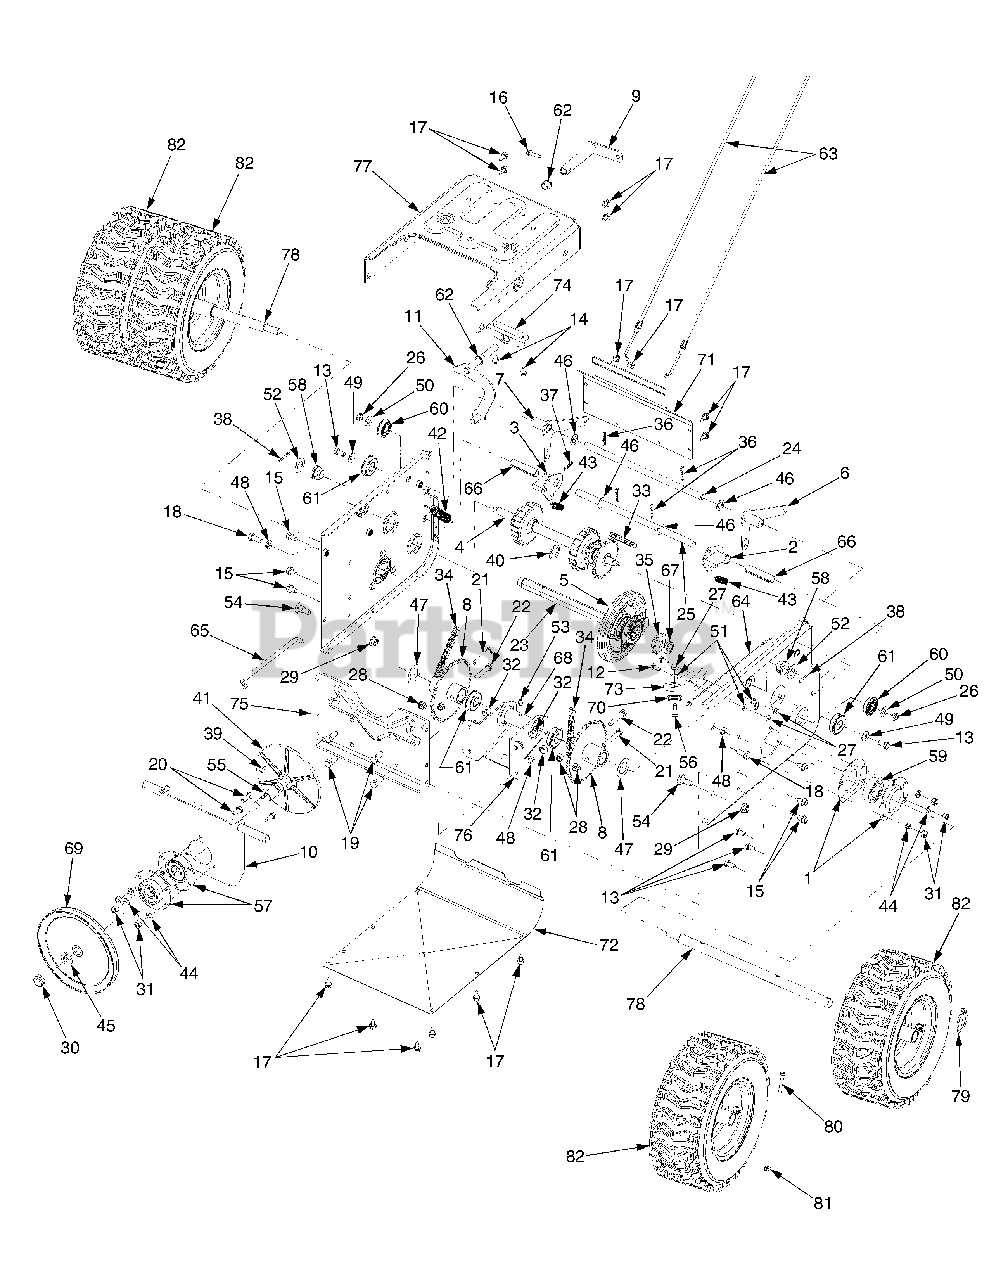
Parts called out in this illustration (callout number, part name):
1	Housing, Bearing
2	Dogg, Steering Drive, LH
3	Dogg, Steering Drive, RH
4	Shaft Assembly, Steering
5	Assembly, Friction Wheel
5	Wheel, Friction
5	Screw, Hex Wash Hd Tapp
6	Bracket, Auger Actuator
10	Bracket, Friction Drive Support
11	Rod Assembly, Shift
12	Screw, Hex Cap, 1/4-28 x .625 GR5
13	Screw, Hex Cap Lock, 5/16-18 x .625 GR5
14	Screw, Hex Wash. Hd. Tapp 1/4-20 x .5
15	Screw, Hex Wash. Hd. Tapp 5/16-18 x .625
16	Screw, Hex Wash. Hd. Tapp 1/4-20 x 1.0
17	Screw, Hex Wash. Hd. Tapp 1/4-20 x .625
18	Screw, Hex Patch Lock, 3/8-16 x .88 GR5
19	Screw, Hex Cap, 3/8-16 x .88 GR5
20	Screw, Hex Cap, 5/16-18 x .75 GR5
21	Screw, Hex Cap, 5/16-18 x 2.0 GR5
22	Screw, Hx Cap, 5/16-18 x 1.75 GR5
23	Shaft, Hex Drive
24	Shaft, Actuator
25	Shaft, Steering Actuator
26	Nut, Hex Insert Jam Lock, 3/8-24 GR5
27	Nut, Hex, 1/4-28 GR5
28	Nut, Hx Flnge Insert Lk, 5/16-18 GrF
29	Nut, Hx Flnge Insert Lk, 3/8-16 GrF
30	Nut, Hx Insert Jam Lk, 5/8-18 GR5
31	Nut, Hex, 5/16-18 GR5
32	Nut, Hex, 3/8-16 GR5
33	Chain, Endless, #41 x 36L
34	Chain, #420 x 40L
35	Sprocket, #41 x 10T
36	Pin, Internal Cotter
37	Pin, Internal Cotter
38	Pin, Cotter, 1/8 x 1.0
39	Key, Hi-Pro, 3/16 x 5/8
40	Ring, Retaining
41	Plate, Drive
42	Spring, Extension
43	Spring, Extension
44	Washer, Lock, 5/16
45	Washer, Lock, 5/8
46	Washer, Flat, .53 x .93 x .05
47	Washer, Flat, Hdn, 1.03 x 1.62 x .03
48	Washer, Lock, 3/8
49	Washer, Belleville, .34 x .872 x .06
50	Washer, Flat, .406 x .875 x .059 .
51	Washer, Lock, 1/4
52	Washer, Flat, .64 x 1.24 x .06
53	Fitting, Lube, 3/16 Drive
54	Screw, Shoulder, .498 x .34:3/8-16
55	Spindle, Drive Plate
56	Screw, Hex Shoulder, 1/4-28:.375
57	Assembly, Bearing/Housing
58	Bearing, Hex Flange
59	Bearing, Self Aligning
60	Bearing, Ball
61	Bearing, Ball
62	Bushing, Flange, .5 ID x .627 OD
63	Cable, Steering
64	Cable, Auger Idler
65	Rod, Drive Clutch
66	Spacer, Split, .514 x .632 x 2.44 .
67	Spacer, .675 x 1.0 x .23
68	Spacer, .6725 x 1.125 x 2.485
69	Pulley, Drive
70	Roller, Cable
80	Screw, Hex Cap, 45" S.T. ONLY 5/16-18 x 2.0 GR5
81	Nut, Hx Flnge Insert Lk, 45" S.T. ONLY 5/16-18 GrF
82	Wheel Assembly - (2) 16 x 6.5 x 8 X-Trac - RH 33" S.T. - 945 SWE
82	Tire - 16 x 6.5 x 8 X-Trac - LH 33" S.T. - 933 SWE & 945 SWE
82	Rim - 16 x 4.8 x 8 X-Trac - RH 28" S.T. - 928 SWE
82	Valve
